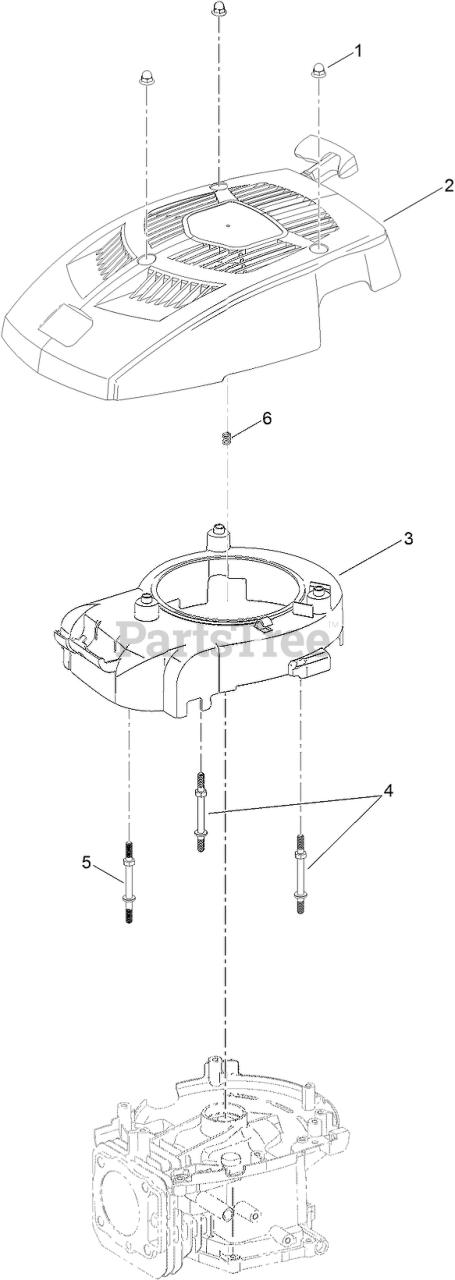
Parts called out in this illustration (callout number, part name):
1	NUT-ACORN
2	RECOIL SHROUD ASM
3	SHROUD-FAN
4	STUD-SHROUD
5	STUD-SHROUD
6	SPRING-COMPRESSION, RECOIL
